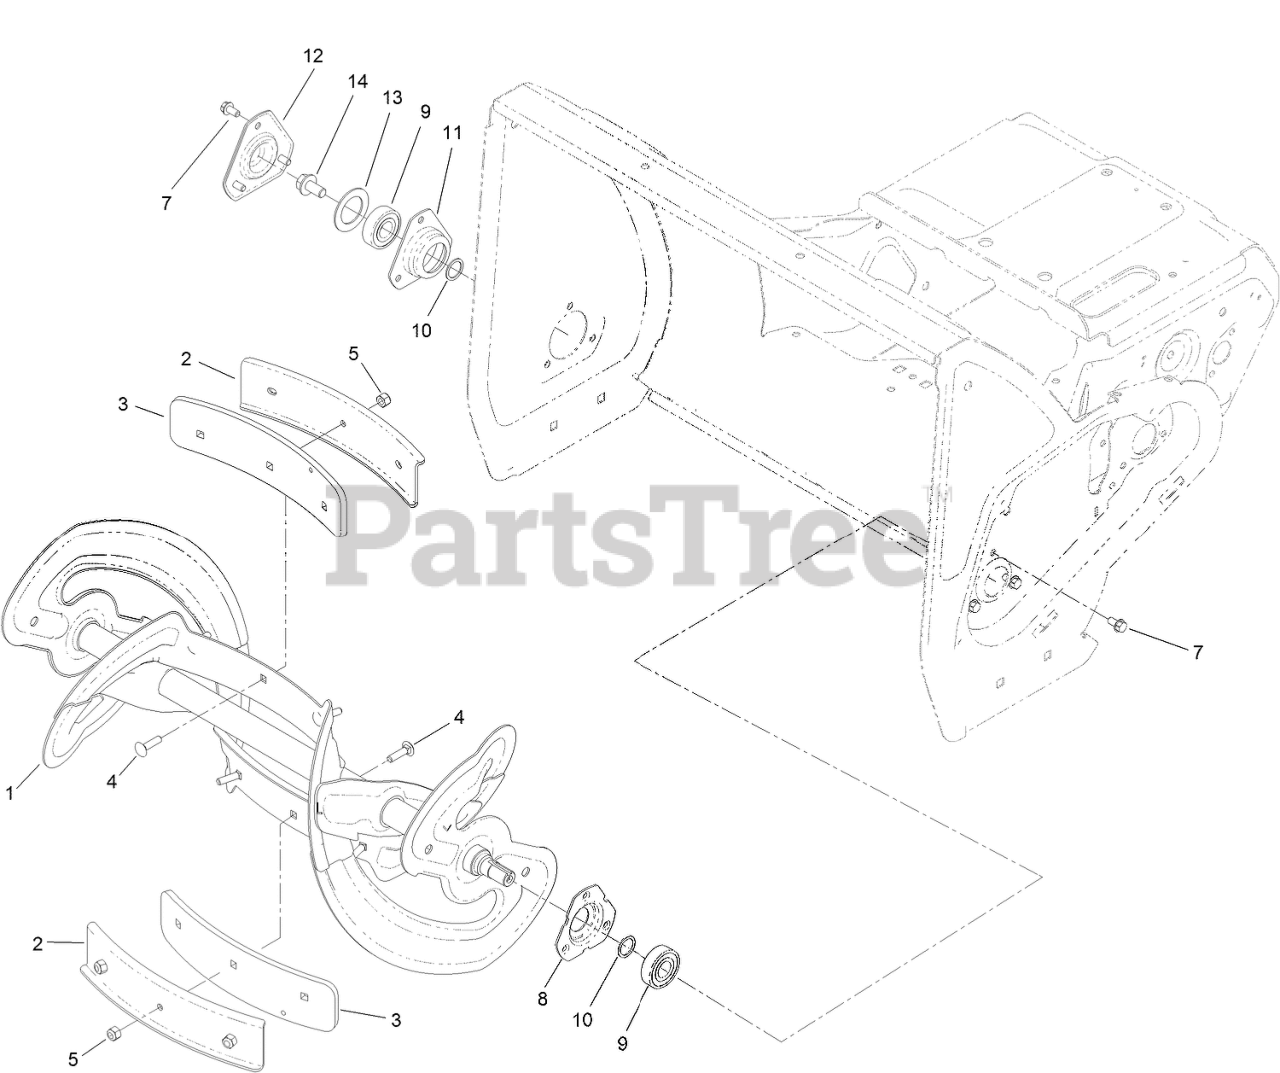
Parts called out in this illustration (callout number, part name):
1	ROTOR ASM
2	SUPPORT-CENTER, ROTOR
3	PADDLE-CENTER
4	SCREW-CARR
5	NUT-LOCK, NI
7	SCREW-HWH
8	FLANGE-BEARING
9	BEARING-BALL
10	WASHER-THRUST
11	BEARING-RETAINER
12	CAP-BEARING
13	WASHER-RUBBER
14	SCREW-HWH
